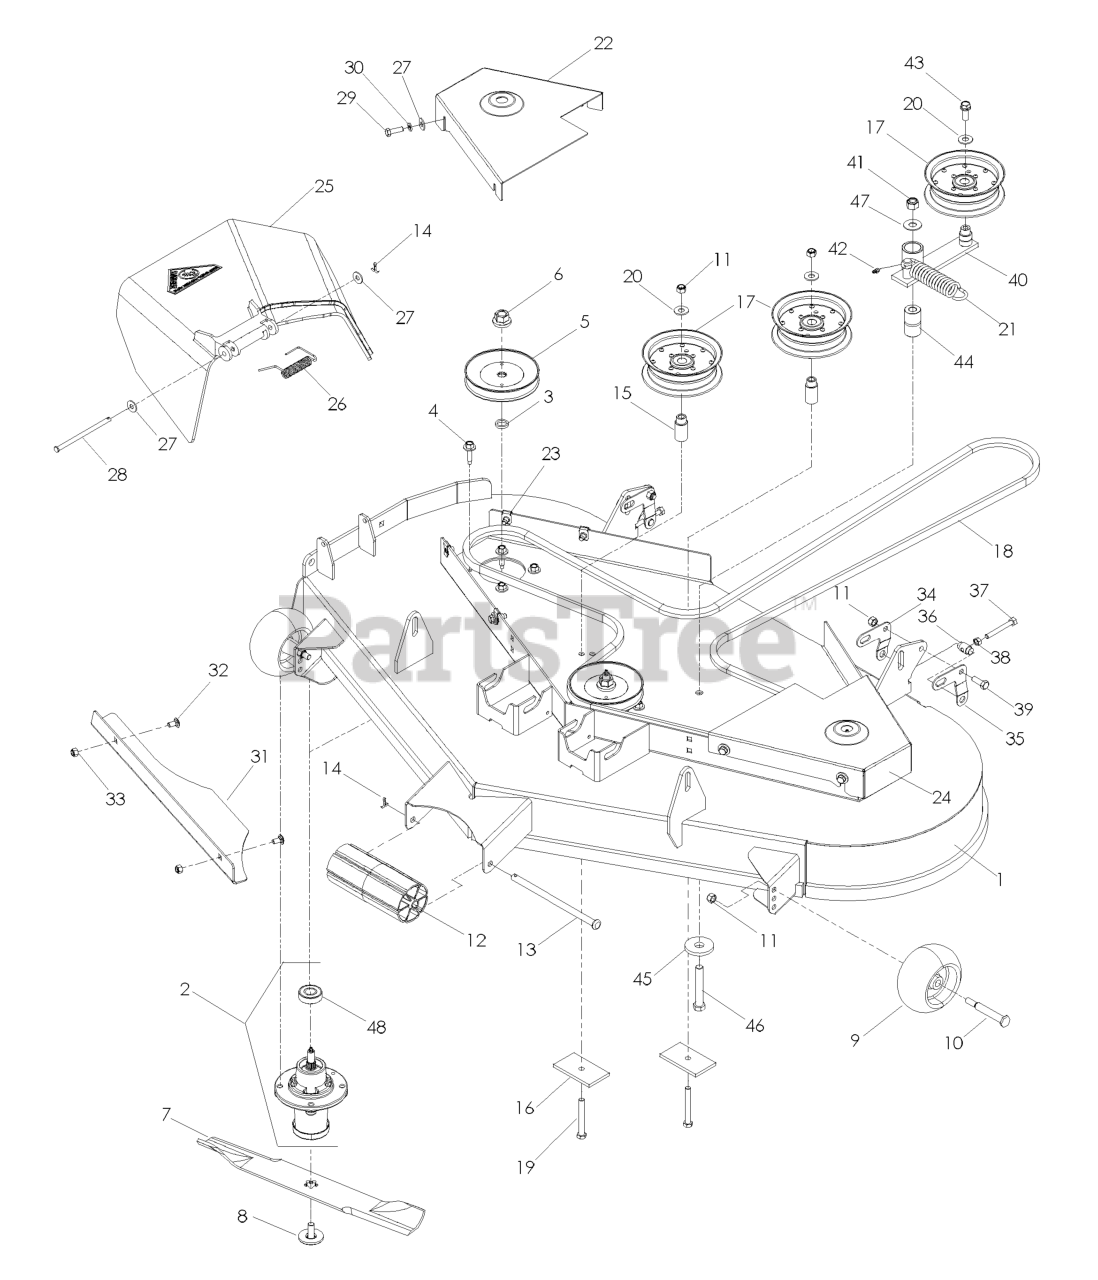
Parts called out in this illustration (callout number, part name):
1	DECK.FAB.W/DECALS.52".MZ.ORANG
2	MANDREL.DECK.ASSEMBLY
3	WASHER-SPACER
4	WASHER HEAD SCREW
5	PULLEY
6	LOCKNUT - 9/16
7	BLADE, 18"
8	BLADE BOLT ASSY-7/16" TB REPL
9	GAUGE WHEEL
10	SHOULDER BOLT 1/2X2-5/8 ZD SPE
11	NUT 3/8-16 NYLOC
12	NOSE ROLLER 48"
13	NOSE ROLLER ROD
14	RP_COTTER PIN 1/8 X 3/4
15	IDLER BUSHING
16	SUPPORT PLATE
17	PULLEY, IDLER
18	BELT.DECK.52".54"
19	HCS 3/8C X 3
20	WASHER 3/8 FLAT
22	BELT SHIELD, RIGHT 52, ORG
23	U-CLIP 5/16-18 NUT RETAINER
24	BELT SHIELD, LEFT 52, ORG
25	DISCHARGE CHUTE 52"
26	SPRING - TORSION
27	WASHER 5/16 FLAT
28	PIN-CLEVIS 5/16 DIA X 5.19 ZD
29	HCS 5/16C X 1
30	WASHER.LOCK.HVY.HLCL.SPR.5/16
31	CONFINEMENT PLATE, 52"
32	CARRIAGE BOLT 5/16C X 5/8"
33	NUT 5/16 NYLOC
34	PITCH, ADJUST, RT
35	PITCH, ADJUST, LT
36	TRUNION, PITCH
37	HCS 5/16-18 X 2 1/2 TPBLT
38	NUT 5/16C HEX
39	HCS 3/8-16X1.GRD.5.ZD
41	NUT 1/2-13 HEX NYLOC ZD
42	ZERK
43	4CS 3/8C X 1 SERRATED HEAD
44	PIVOT BUSHING
45	WASHER, SUPPORT
46	HCS 1/2C X 3 1/4
47	WASHER 1/2 FLAT
48	BAFFLE LEFT 54
